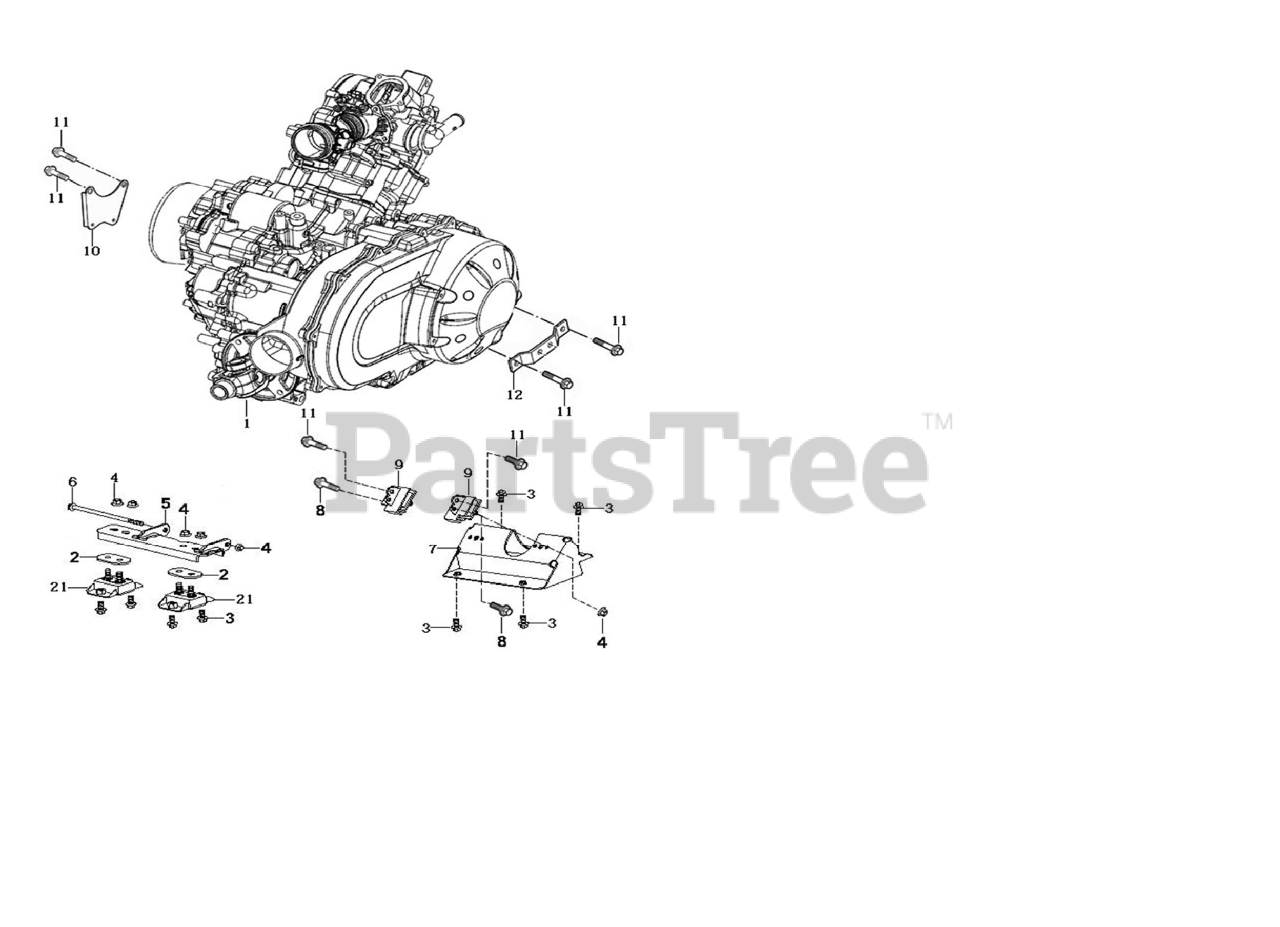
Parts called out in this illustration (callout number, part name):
1	ENGINE ASSEMBLY - 750
1	ENGINE ASSEMBLY - 550
2	ENGINE DAMPENING WASHER
3	Hexagon Flange bolt M10x1.25x20
4	LOCK NUT M10x1.25
5	ENGINE MOUNTING BRACKET PLATED ASSEMBLY?
6	BOLT HExAGON FLANGE HEAD M10x1.25-175
7	ENGINE MOUNTING BRACKET PLATED ASSEMBLYII
8	Hexagon Flange Bolt M6x16
9	ENGINE MOUNTING REAR ASSEMBLY
10	ENGINE MOUNTING BRACKET PLATED ASSEMBLY IV
11	Cross Large Plate Head Screw M8x16
12	ENGINE MOUNTING BRACKET PLATED ASSEMBLY III
